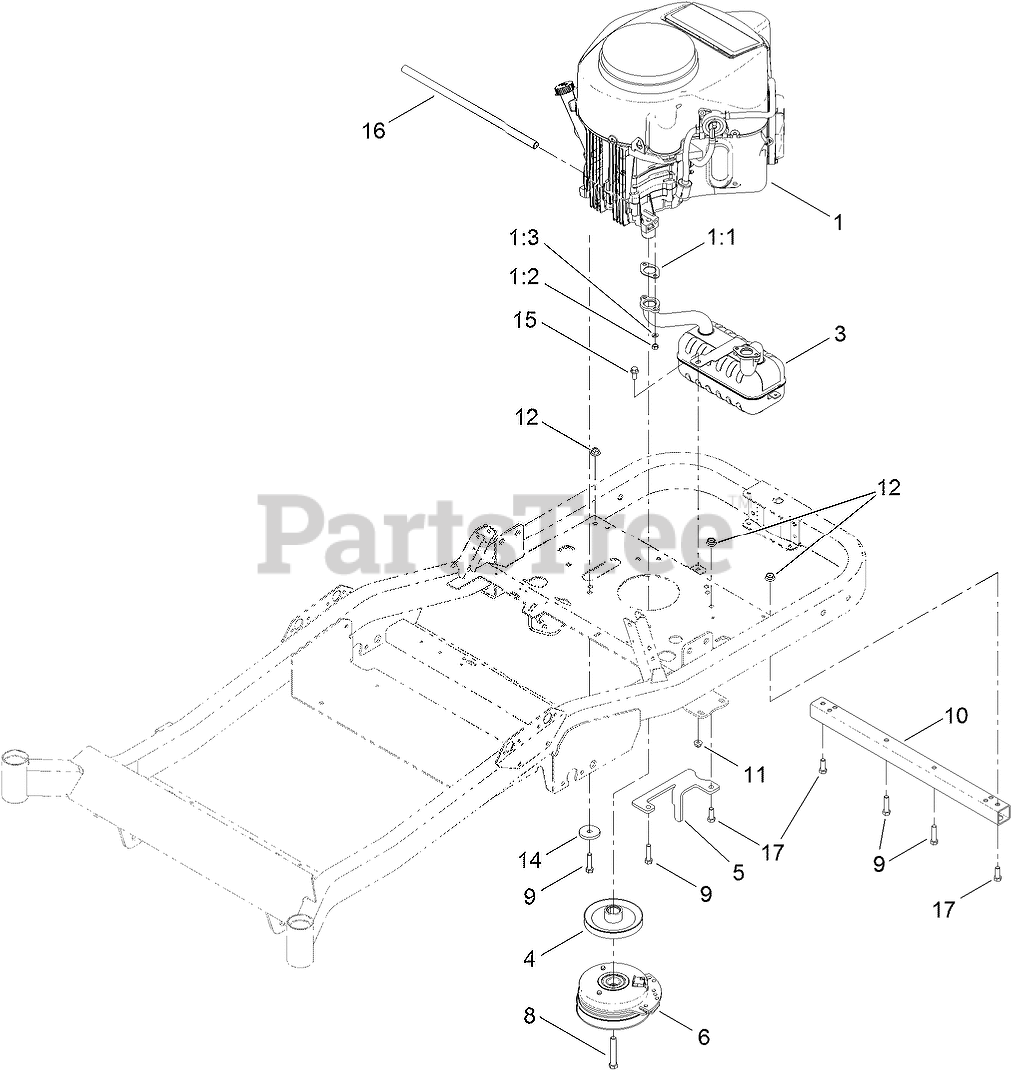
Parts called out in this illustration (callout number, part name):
1:1	GASKET-EXHAUST
1:3	WASHER-LOCK
3	MUFFLER-KAWASAKI TWIN
4	PULLEY-ENGINE
5	BRACKET-STOP, PTO
6	CLUTCH-PTO
8	SCREW-HH
9	BOLT-HH
10	TUBE-STIFFENER
11	NUT-HF, NI
12	NUT-HF, NI
14	WASHER-PLAIN
15	SCREW-HHF
16	TUBE-DRAIN, OIL
17	SCREW-HH
